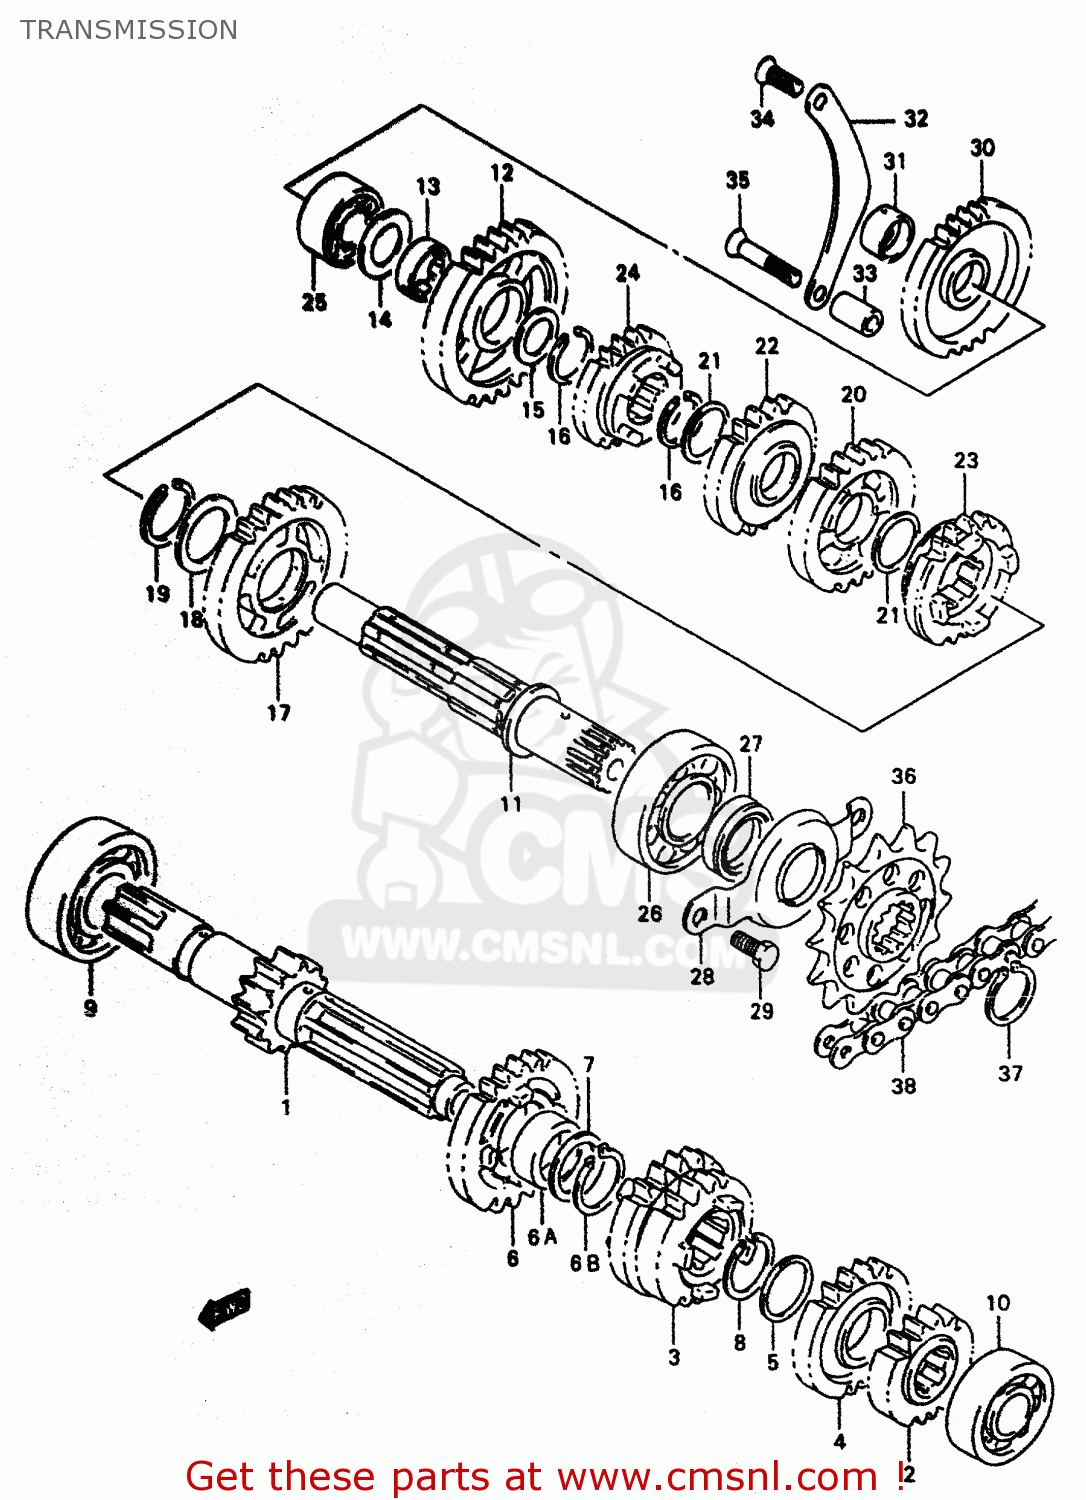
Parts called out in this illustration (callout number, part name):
1	SHAFT,COUNTER(NT:12)
2	GEAR,SECOND DRIVE (NT:15)
3	GEAR,3RD & 4TH DRIVE(NT:18/18)
4	GEAR,5TH DRIVE(NT:21)
5	SHIM(22X26X1)
6	GEAR,6TH DRIVE(NT:23)
6A	BUSH(22X26X9)
6B	CIRCLIP
7	SHIM(22X30X1)
8	CIRCLIP
9	BEARING 20X52X15
10	BEARING
11	SHAFT,DRIVE
12	GEAR,1ST DRIVEN(NT:30)
13	BUSH,1ST DRIVEN GEAR
14	WASHER
15	SHIM(22X30X1)
16	CIRCLIP
17	GEAR,2ND DRIVEN(NT:26)
18	SHIM(25X34X1)
19	CIRCLIP
20	GEAR,3RD DRIVEN(NT:24)
21	SHIM(22X28X1)
22	GEAR,4TH DRIVEN(NT:20)
23	GEAR,FIFTH DRIVEN (NT:20)
24	GEAR,6TH DRIVEN(NT:19)
25	BEARING(17X40X17.5)
26	BEARING(22X56X16)
27	SEAL,OIL(22X34X7)
28	RETAINER,DRIVE SHAFT OIL SEAL
29	BOLT
30	GEAR,KICK STARTER IDLE(NT:27)
31	BUSH,KICK STARTER IDLE GEAR
32	RETAINER,KICK IDLE GEAR
33	SPACER(6.5X12X21)
34	SCREW ,6X16
35	SCREW
36	SPROCKET(NT:15)
37	CIRCLIP
38	CHAIN(DID520VC5,110LE)
